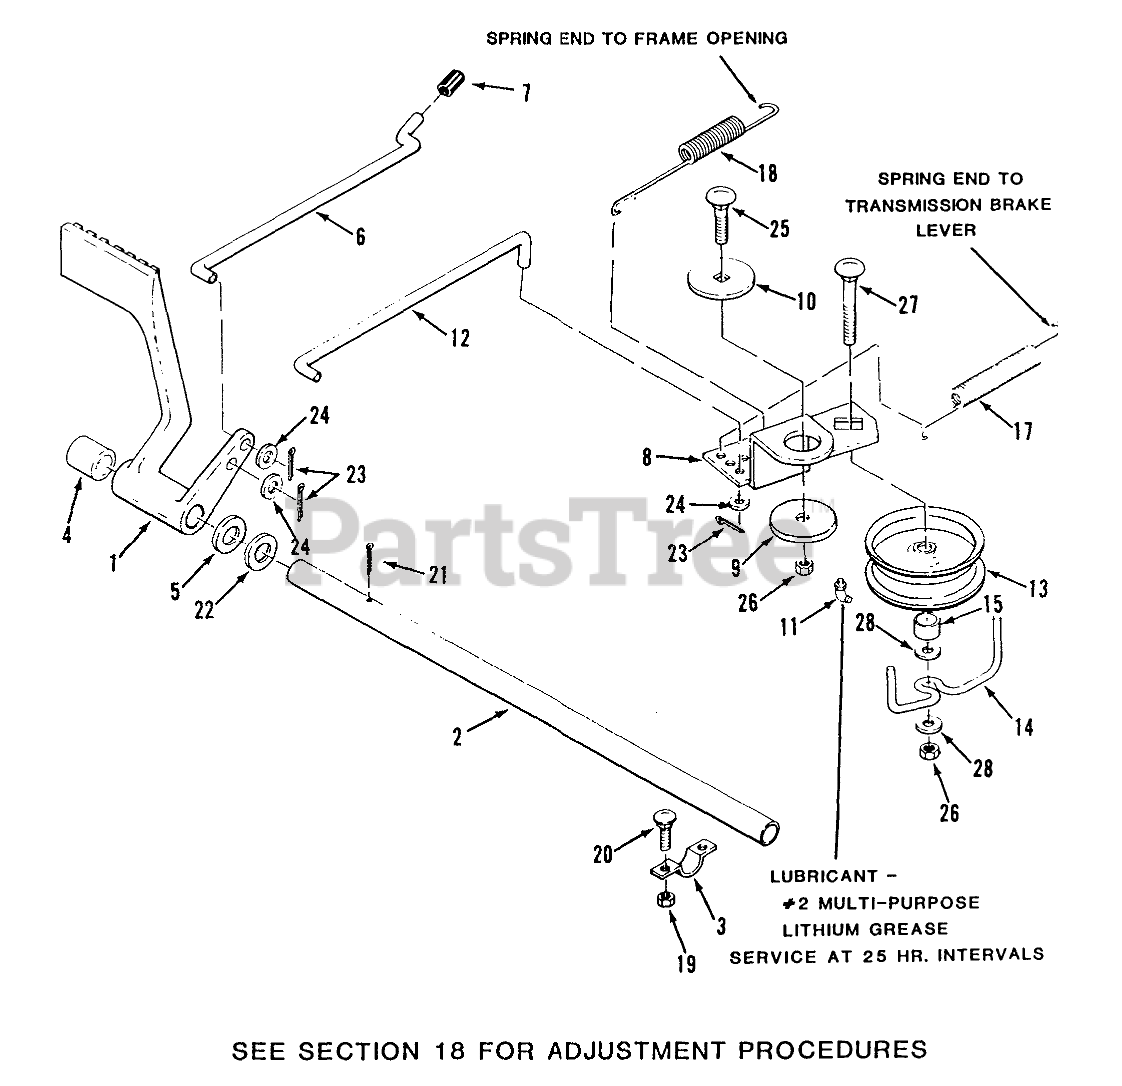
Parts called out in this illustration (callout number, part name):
1	PEDAL BRAKE R
2	SHAFT PEDAL
3	CLAMP
4	SPACER
5	WASHER-WAVE
6	Lock Rod
8	ARM-IDLER R
9	BUSHING
10	WASHER-BEARING
11	Fitting-Grease
12	ROD-CLUTCH/BRAKE B
13	PULLEY IDLER
14	GUIDE-BELT
15	SPACER
17	SPRING - BRAKE
18	SPRING
19	Nut
20	Bolt
22	Washer
23	Cotter Pin
24	WASHER 5/16 SAE
25	Bolt
26	NUT
27	Carriage Bolt 3/8-16 x 2-1/4
28	Washer
